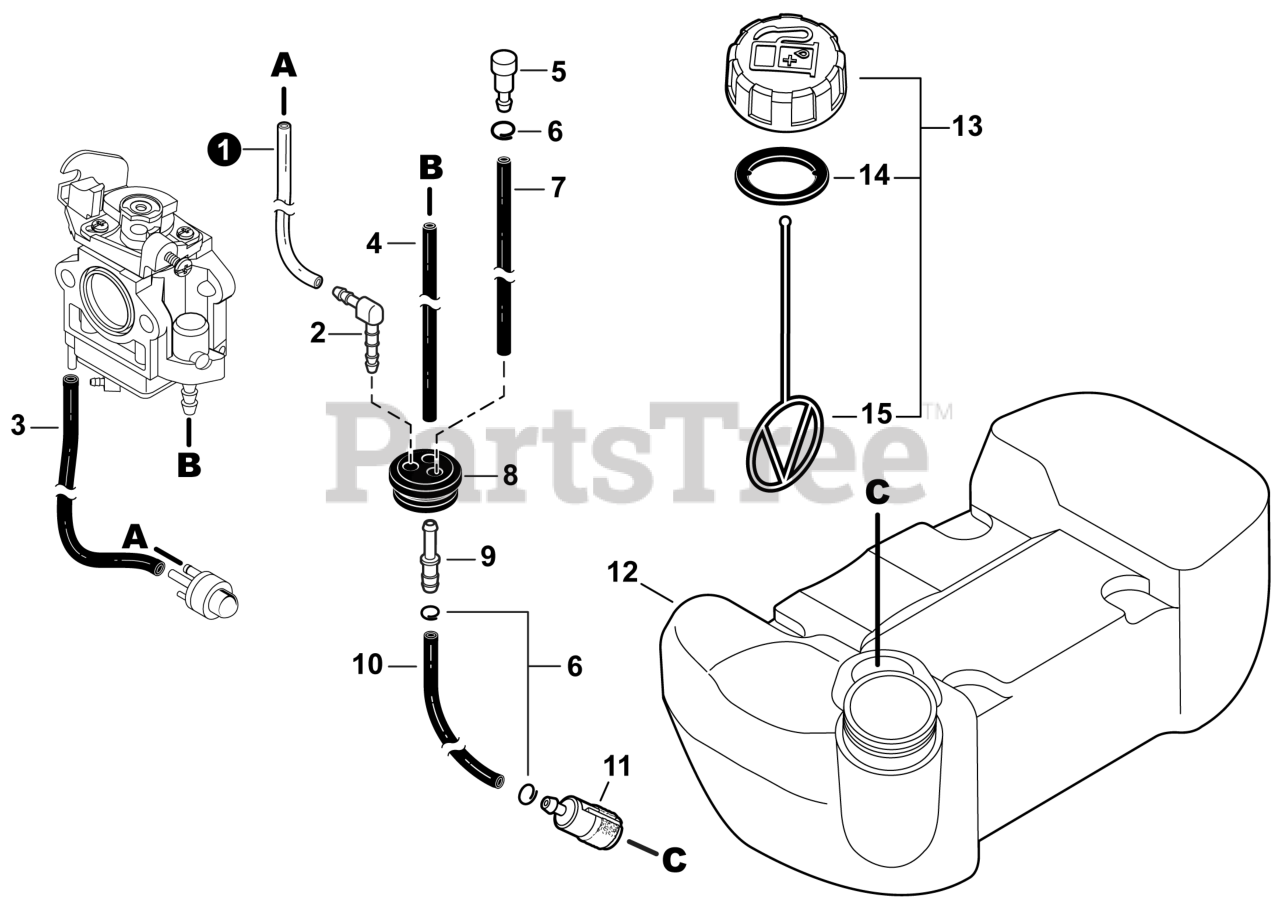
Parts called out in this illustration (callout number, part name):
1	PIPE, FUEL 3x6x60 CLEAR
2	CONNECTOR, PIPE
3	PIPE, FUEL 2.4x5x80 BLACK
4	PIPE, FUEL 3x5.5x61 BLACK
5	VENT ASSY
6	CLIP 6.5 MM
7	PIPE, FUEL 3x6x120 BLACK
8	GROMMET, FUEL
9	CONNECTOR, PIPE 5x3.5
10	PIPE 3x6x125 BLACK
11	FILTER, FUEL
12	TANK, FUEL
13	CAP ASSY, FUEL
14	GASKET, FUEL CAP
15	CONNECTOR, CAP L= 123
